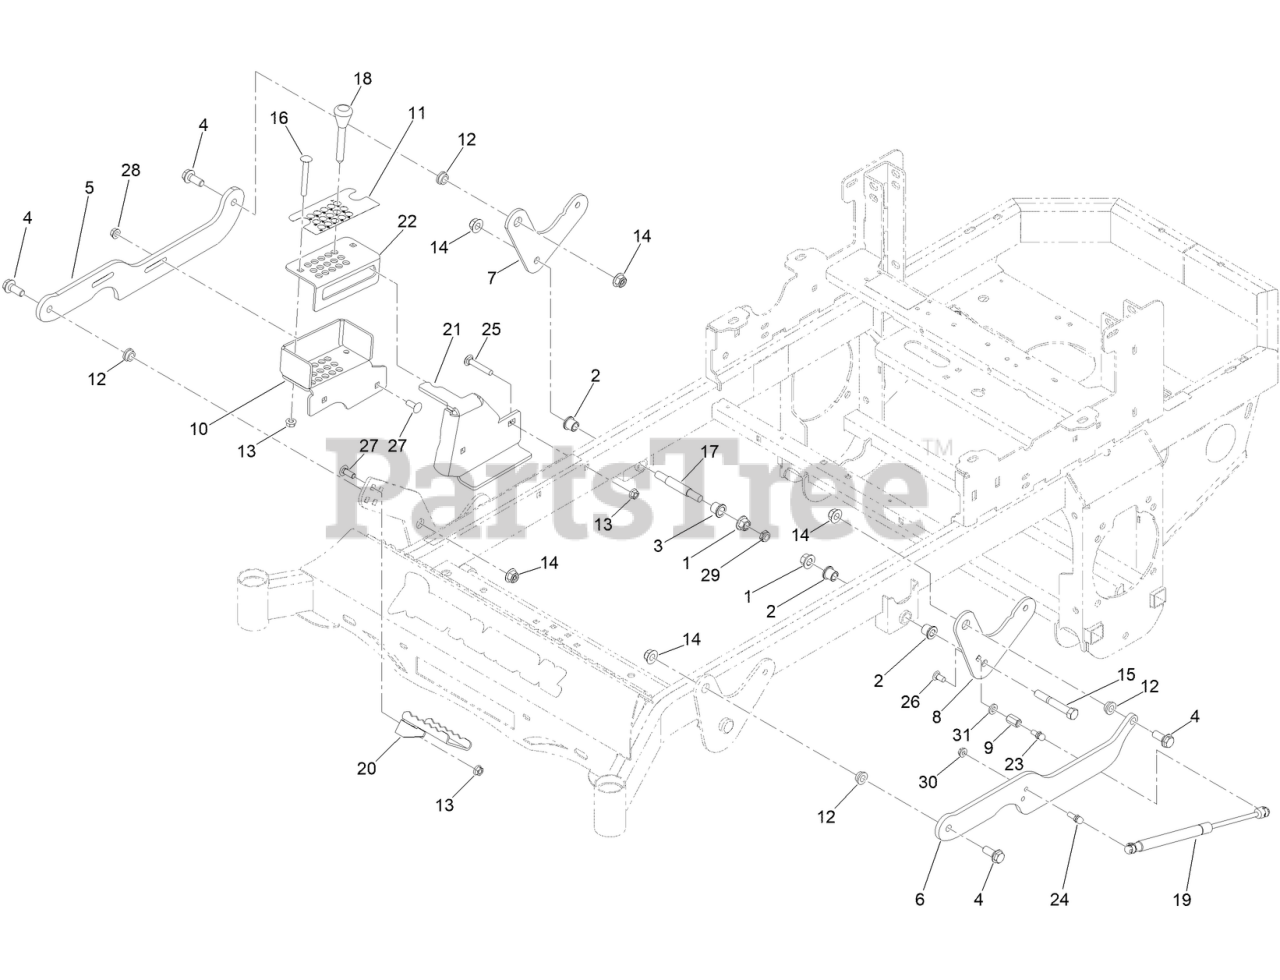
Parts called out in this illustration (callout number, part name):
1	NUT-LOCK
2	BUSHING-FLANGE
3	BUSHING-FLANGE
4	SCREW-HHF
5	2024 DECK HGHT ARM RT LINK
6	LINK-DECKLIFT
7	ARM-DECKLIFT REAR (1/4")
8	ARM-DECKLIFT REAR (1/4")
9	HEX COUPLING NUT - REDUCER (3/8" TO 5/16
10	2022 DHI PIN ARM LINK BOTTOM BRACKET
11	DECAL-HEIGHT OF CUT
12	1/2IN ID X 3/4IN OD X 3/8IN FLANGE BUSH
14	1/2-13 HEX FLANGE 2-WAY REV CNTR L/NYZ
15	1/2-13 X 3-1/2 HEX C/S GR 5 ZINC YELLOW
16	(3/8-16 X 3 CARRIAGE BOLT (GR.5) ZC/YEL)
17	RR DECK HEIGHT BOLT (MACHINED)
18	MAGNETIC PIN FOR STAND ON MWR
19	RZ DECK ASSIST GAS SPRING
20	MWR DECK HEIGHT FOOT PEDAL BLACK
21	2022 DECK LOCK PIN TUBE BRKT BLACK
22	2022 DHI PIN ARM LINK TOP BRKT BLACK
23	5/16-18X1.286 DAMPER BALL STUD (.562 TL)
24	5/16-18X1.286 DAMPER BALL STUD (.562 TL)
25	SCREW-CARR
26	3/8 X 3/4IN GR 8 CARR BOLT ZINC
27	3/8-16 X 1 CARRIAGE BOLT YZ GR.8
28	3/8-16 HEX FLANGE NUT W/SERR ZINC YELLOW
29	NUT-HEX
31	5/16IN USS FLAT WASHER (3/8 ID X 7/8 OD)
